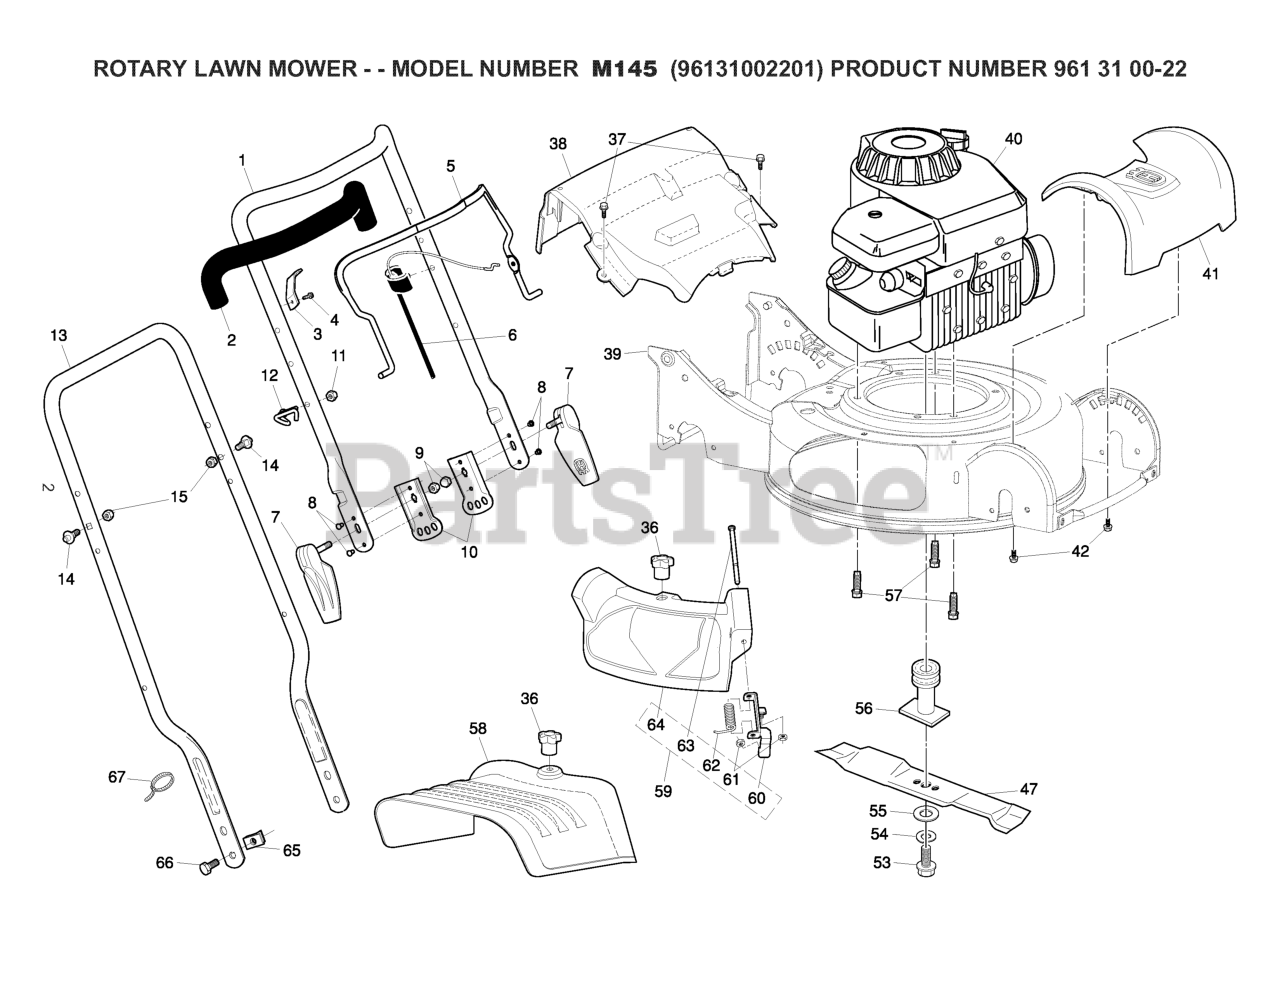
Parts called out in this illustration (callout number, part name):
2	GRIP, FOAM
5	BAIL CONTROL
6	CONTROL.ZONE.ASM
7	ASM.QUICK.RELEASE
9	Locknut, Hex 1/4-20
10	BRACKET.ADJ.3POS.GREY
11	NUT
12	RB GUIDE.ROPE.STD.BLK.ZIN WSL
14	STUD.QUICK.ADJUST
15	NUT.LOCK.5/16-18
36	KNOB.MULCH.DOOR
37	SCREW, HEX WASHER HEAD
42	SCREW.HWH.13-16-5.8.BZP
53	BOLT.HD.HEAD.3/8-24X2.50 (2 2)
54	LOCKWASHER
55	WASHER,HARDEN
57	BOLT 3/8-16X1-1/8
61	NUT.HEX.FLANGE.1/4
62	SPRING.MULCH.DOOR
63	ROD.HINGE.1/4"3.82"
64	DOOR.MULCH.GREY
67	TIE GUIDE
